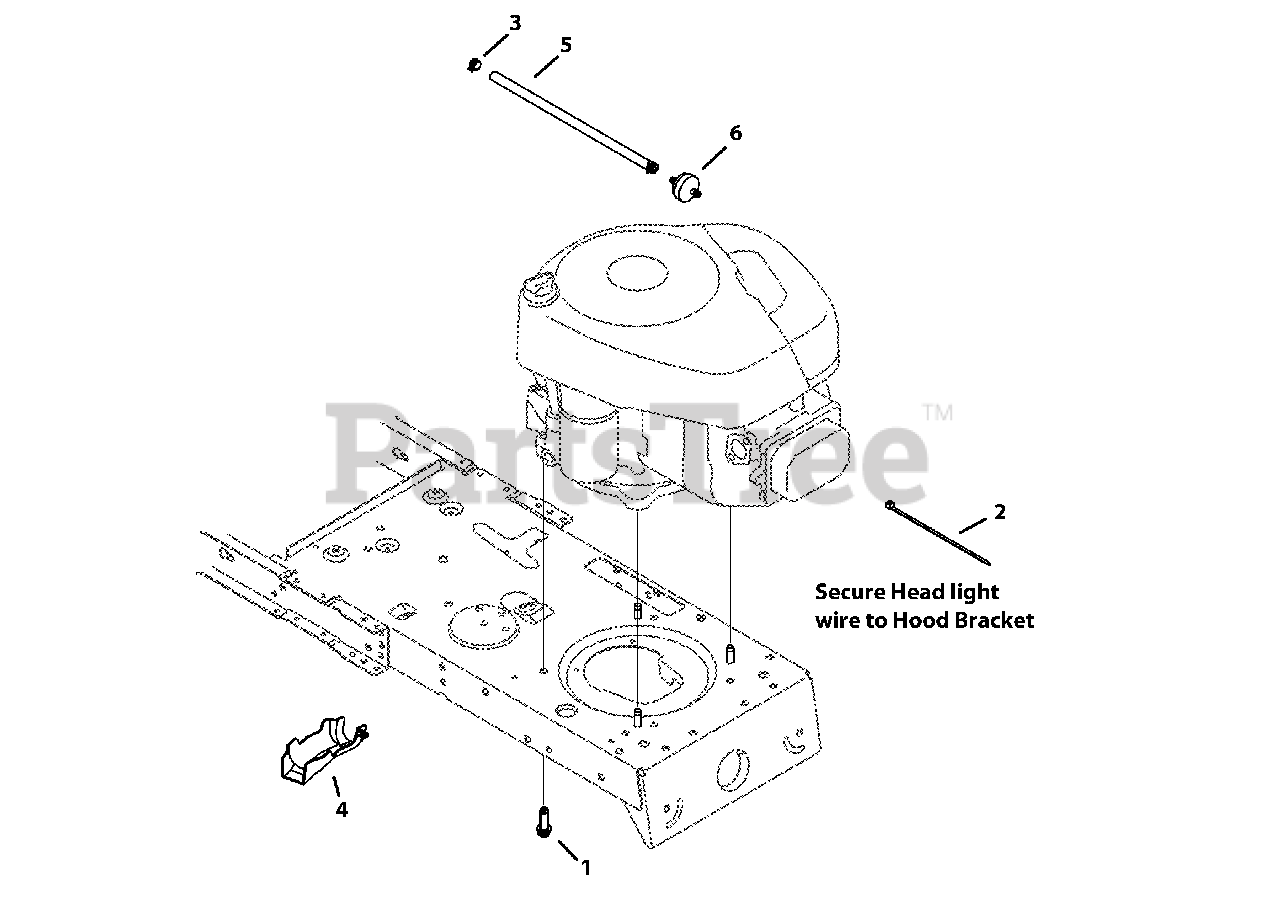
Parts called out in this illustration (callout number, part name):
1	Screw, 3/8-16 x 1.0
2	Cable Tie
3	Clamp Hose, .490 diameter
4	Oil Drain Sleeve
5	Fuel Hose, Low Permeation
6	Fuel Filter
